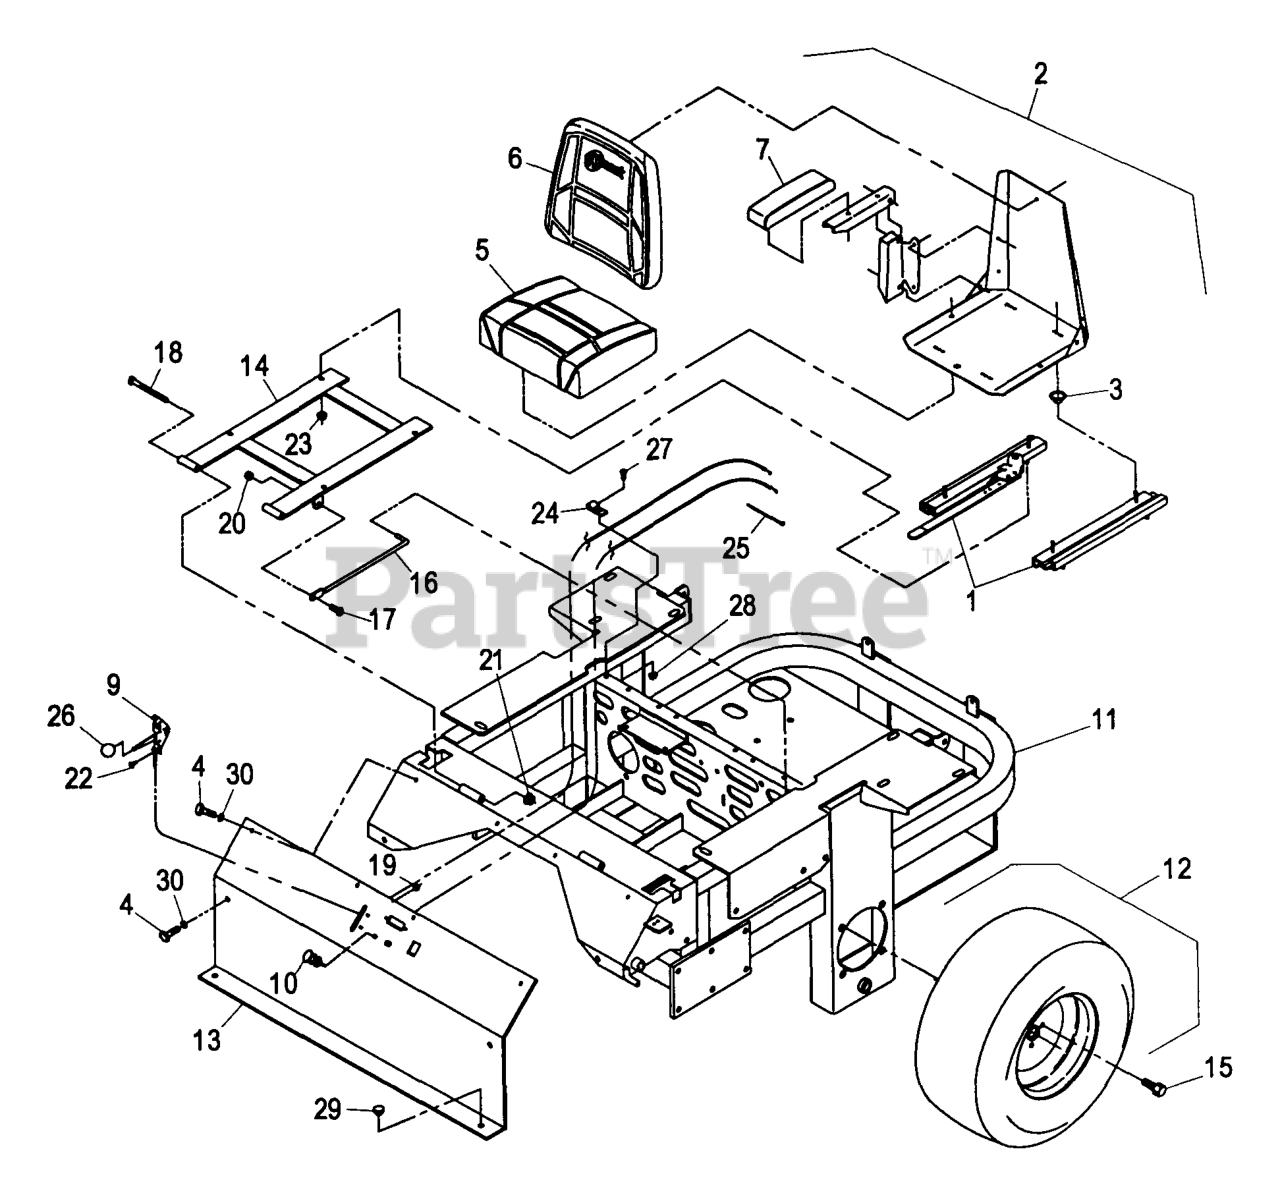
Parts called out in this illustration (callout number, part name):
3	SPACER-TRACK
9	THROTTLE CABLE ASM
10	CONTROL-CHOKE
15	WHEEL BOLT
16	ROD-HOLDUP, SEAT
22	BOLT-CARR
24	CLIP-LOOM
25	TIE-PLASTIC
26	KNOB-BALL
